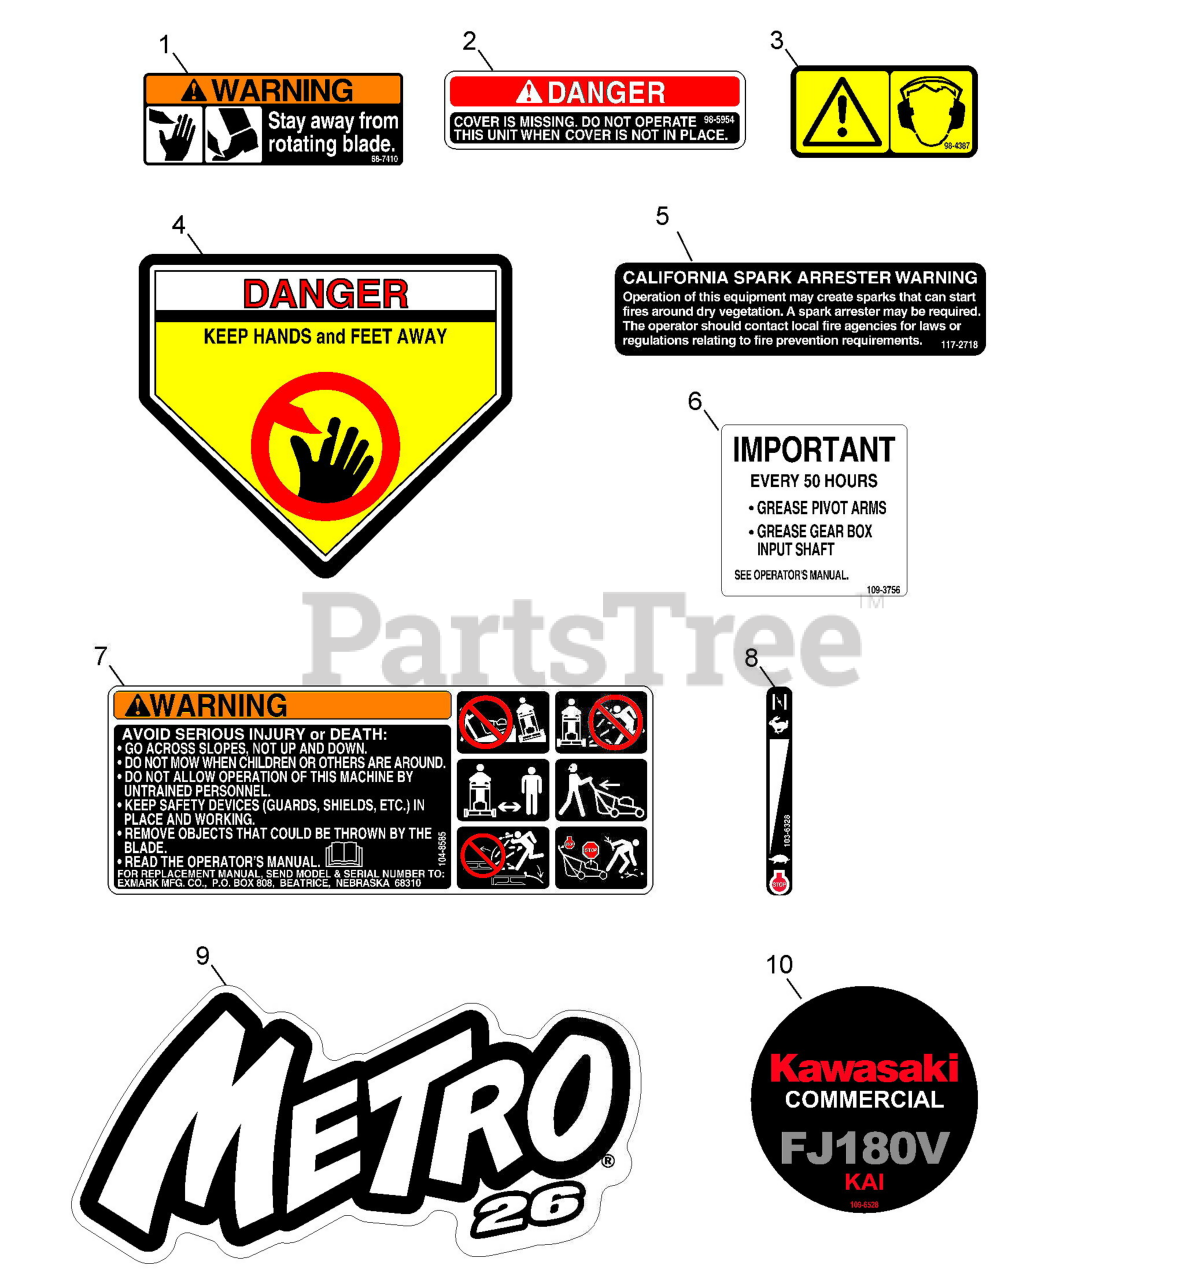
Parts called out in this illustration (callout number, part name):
1	DECAL-BLADE
2	DECAL-COVER, MISSING
3	DECAL-PROTECTION, EAR
4	DECAL-DANGER
5	DECAL-ARRESTER, SPARK
6	DECAL,SERVICE M26
7	DECAL-WARNING
8	DECAL-THROTTLE / CHOKE
9	DECAL,METRO 26
